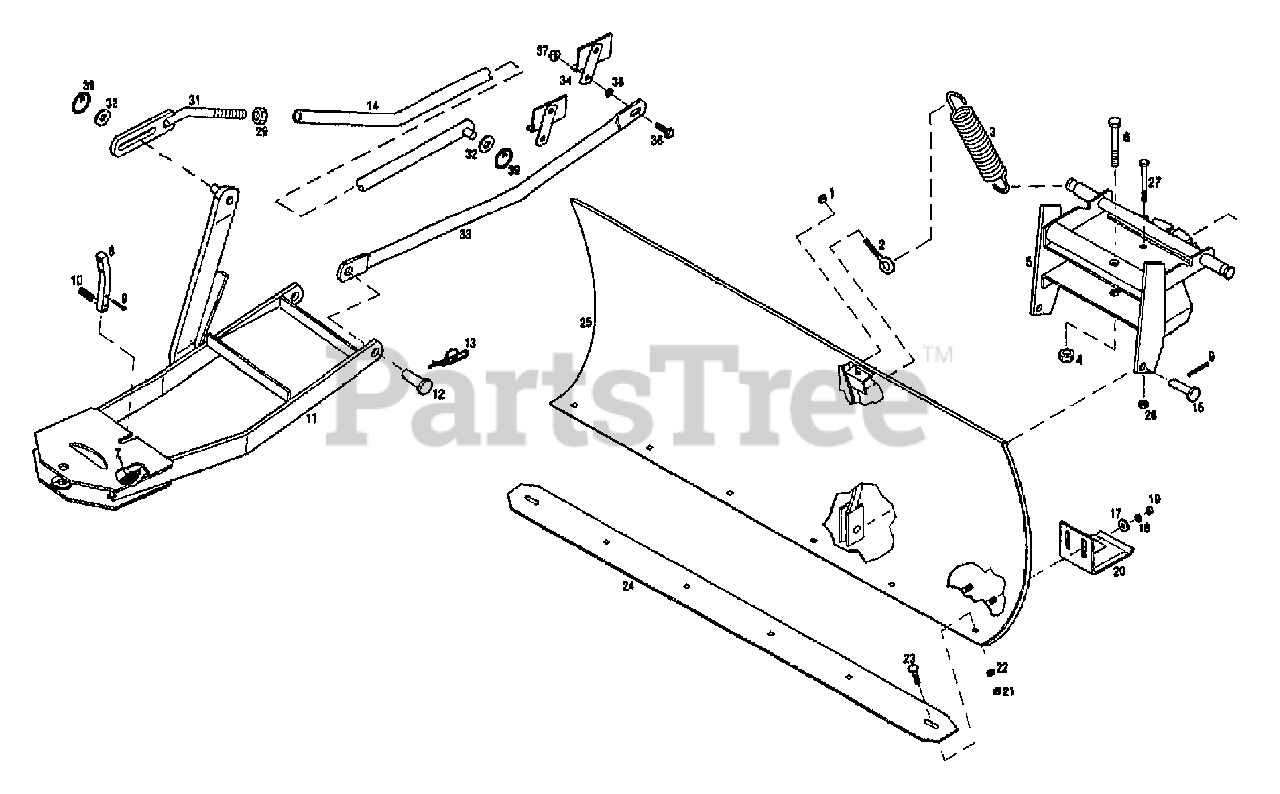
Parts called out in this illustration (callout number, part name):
1	NUT-TOP/LK 5/16-18 ZP
2	BOLT-EYE 5/16-18X2.75 ZP
4	NUT-LOCK
6	SCR-HH 5/8-11X3.0 G5
9	PIN-COTTER .125 X .75 ZP
10	PIN-DRIVE .125X1.0
12	PIN-CLEVIS
13	RING-COTTER
14	ASSM-LIFT TUBE
15	PIN-CLEVIS .5X1.06 ZP
17	WASHER-FLAT 3/8 SAE
18	WASHER-LK .375 @ DEPL
19	NUT-HEX 3/8-16 ZP
20	SHOE-SKID
21	NUT-HEX 5/16-18 ZP
22	WASHER-LK .312 ZP
23	SCR-CARR 5/16-18X1.0 G2 ZP
24	BLADE-SCRAPER
27	SCR-HH 3/8-16X2.75 G5 ZP
28	NUT-LOCK 3/8-16
31	ASSM-LIFT ROD
32	WASHER-1.06X.531X.1 ZP
33	ASSM-STRUT SUPPORT
34	ASSM-BRKT RH
36	SCR-HFLK 3/8-16X1.00 ZP
37	NUT-HFLK 3/8-16 ZP
39	RING-CIRCLE COTTER
